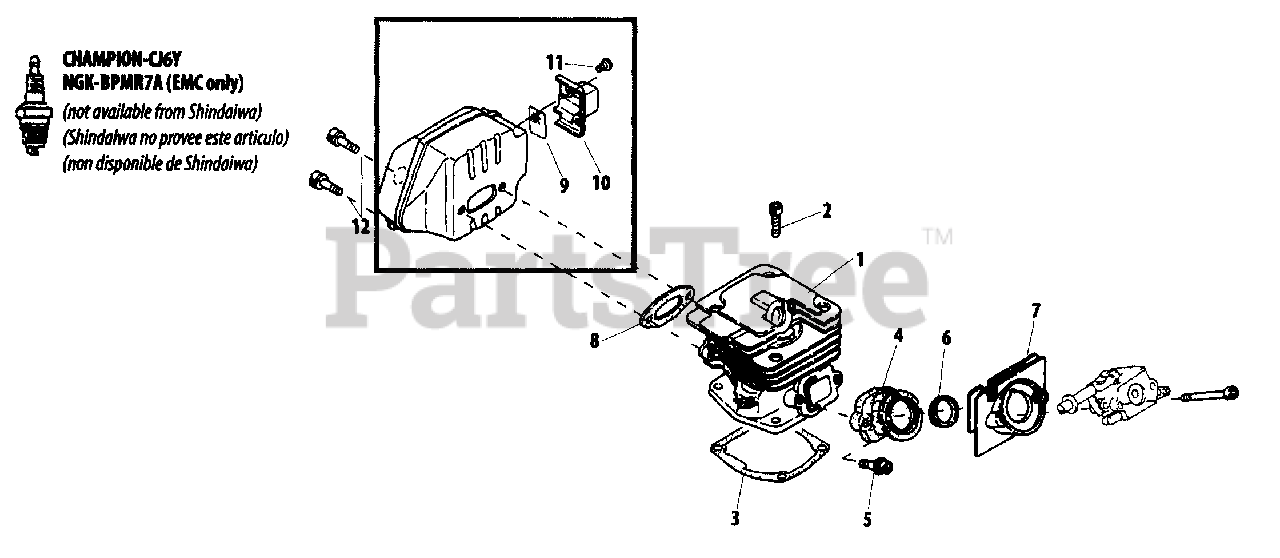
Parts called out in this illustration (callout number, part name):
1	CYLINDER
3	GASKET, CYLINDER
4	BOOT
5	BOLT, ADHESIVE M4×14
6	COLLAR 16
7	INSULATOR, INTAKE
8	GASKET, EXHAUST
9	SCREEN, SPARK ARRESTER
10	GUIDE, EXHAUST
11	SCREW M4×6
12	BOLT M5×16
